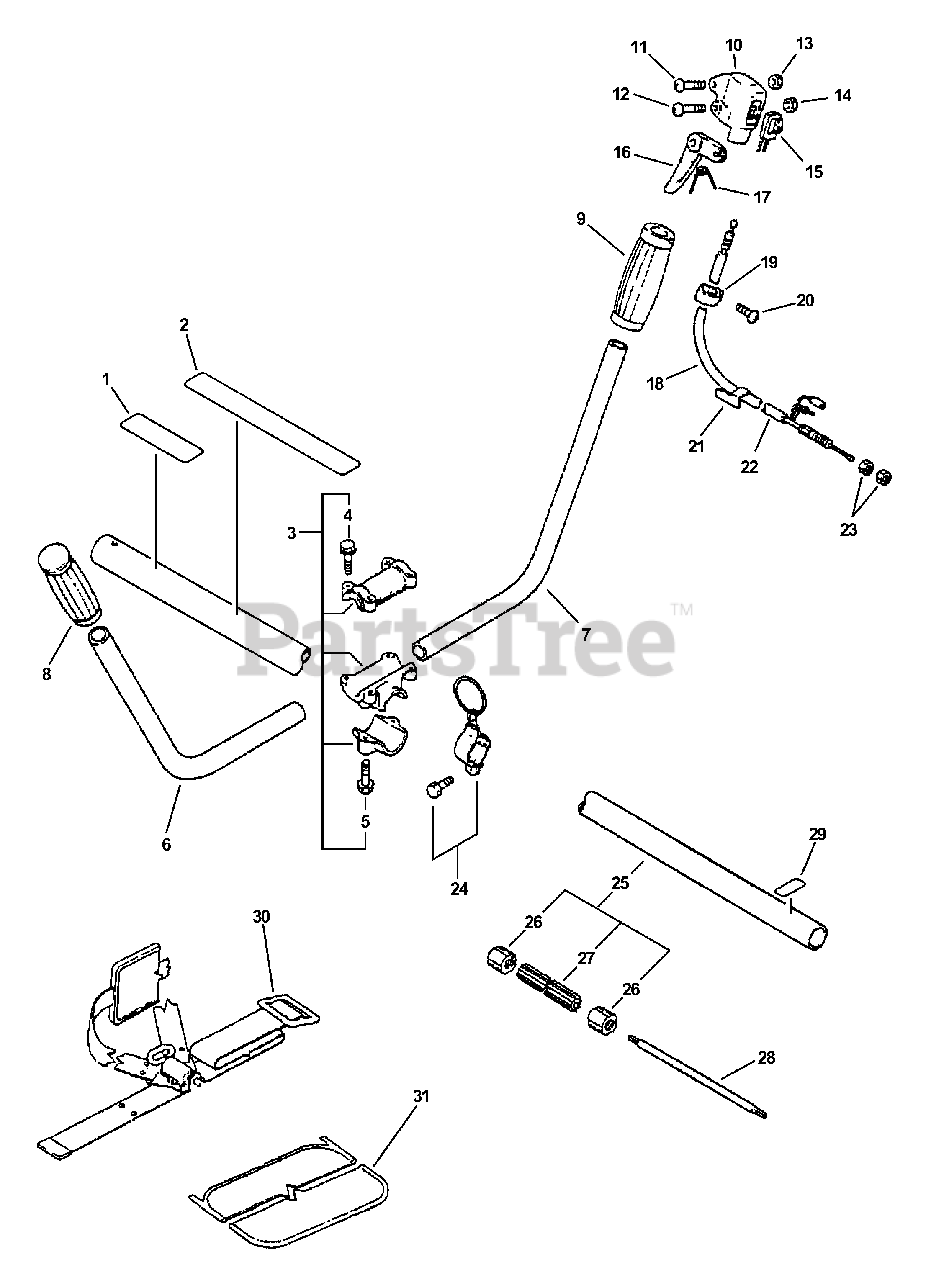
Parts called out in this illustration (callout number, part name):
1	LABEL, CAUTION
2	LABEL, CAUTION
3	BRACKET KIT, HANDLE
4	BOLT - 5×25
5	BOLT - 6×30
6	HANDLE, LEFT
8	GRIP, HANDLE
10	BODY, THROTTLE CONTROL
11	SCREW 5×25
13	NUT, LOCK M5
14	NUT M5
15	IGNITION SWITCH ASSY
16	TRIGGER, THROTTLE
18	CABLE, THROTTLE
20	SCREW 5×10
22	TUBE
23	NUT 6 MM
24	HANGER SET, HARNESS
25	MAIN PIPE ASSY 25×1500
27	LINER, FLEXIBLE 21.6×1420
28	DRIVESHAFT - FLEXIBLE L= 1522
29	LABEL - ALIGNMENT
30	SHOULDER STRAP ASSY
31	PAD, HIP
